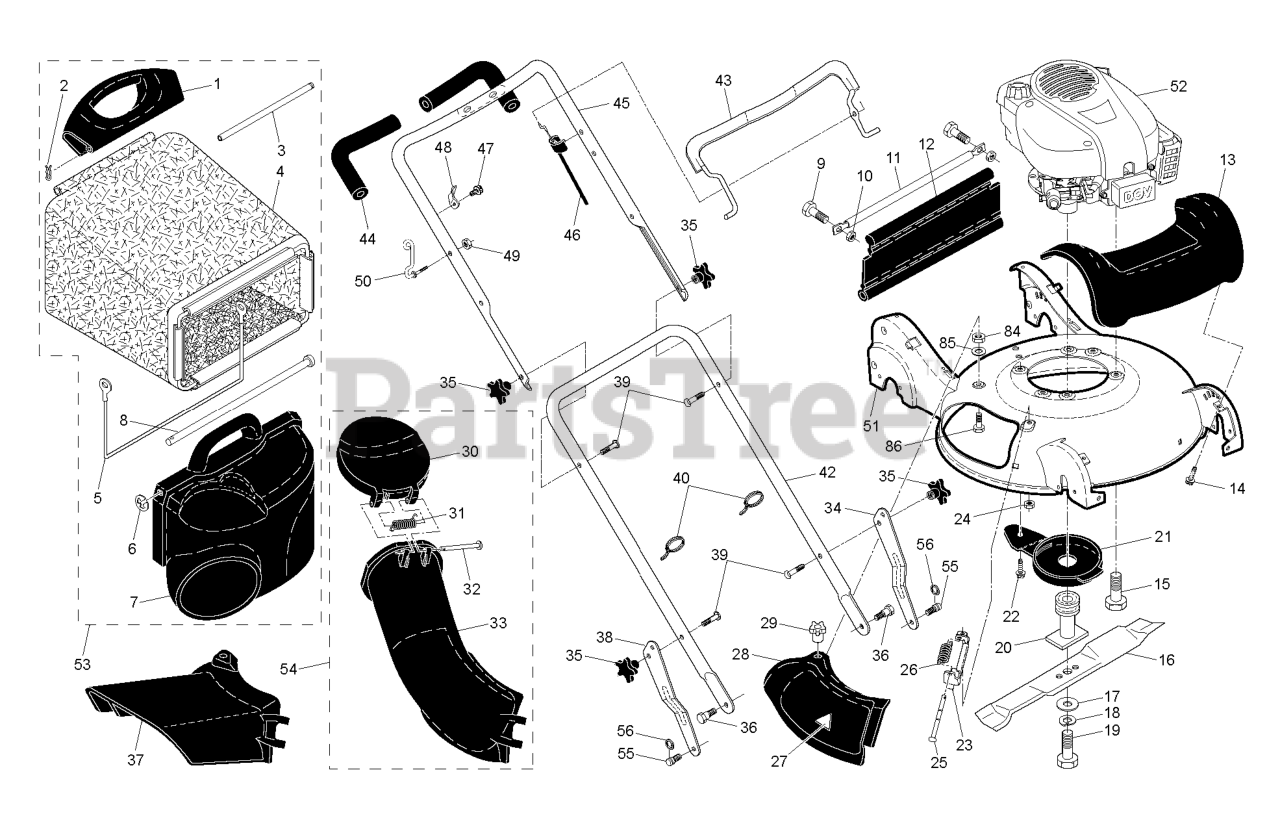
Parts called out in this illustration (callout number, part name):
1	HANDLE.GRASSBAG.REAR.H-GRAY
2	COTTER PIN (3 2)(2 2MC)
3	ROD.REAR.HANDLE.YELLOW
5	FRAME, GRASSBAG
7	DOOR, GRASSBAG
8	ROD, PIVOT
10	LOCKNUT.NYLOC.1/4-20
11	TUBE, REAR SKIRT
13	COVER.FRONT.21.HV.H-GRAY
14	SCREW, HEX WASHER HEAD
15	BOLT 3/8-16X1-1/8
16	Blade, 21"
17	WASHER,HARDEN
18	LOCKWASHER
19	BOLT.HD.HEAD.3/8-24X2.50 (2 2)
20	ADAPTER.BLADE
21	DEBRIS SHEILD
22	SCREW 1/4X20
23	BRACKET.ASM.HINGE
24	NUT.HEX.FLANGE.1/4
25	ROD.HINGE.1/4"3.82"
26	SPRING.MULCH.DOOR
27	DECAL.INTERNATIONL.CUTFINGER
28	MULCHER DOOR
29	KNOB.MULCH.DOOR
30	CHUTE.DOOR.21.HV.H-GRAY
32	ROD.HINGE.1/4"3.82"
33	DISCHARGE CHUTE PLASTIC
34	ADJUSTMENT BRACKET, LOWER LH
35	KNOB.HANDLE.PLASTIC.STAR.BLACK
36	SCREW.5/16X.680.TRIM.H
37	GUARD.CLIP.ON.21.HV.GRAY
38	BRACKET.ADJ.LOWER.HDL.RT.GREY
39	BOLT, HANDLE 5/16-18X1.75
40	TIE GUIDE
42	HANDLE.LOWER.GREY
43	BAIL CONTROL
44	GRIP.HANDLE.FOAM.WIDE.(1 SIDE)
45	HANDLE.ASM.UPPER.W/GRIP
46	CABLE.MZR.SNAP-IN
48	BRACKET
49	NUT
50	GUIDE.ROPE.WALK.MOWER
53	Grassbag Assembly, Complete
54	CHUTE.LOWER.ASM.WALK.MOWER
55	STUD.SHOULDER.T45.BZP
56	E-RING 7/16 RE
81	SCREW.HWH.13-16-5.8.BZP
84	NUT, HEX
85	LOCKWASHER
86	BOLT.CARRIAGE.1/4-20 X 7/8
